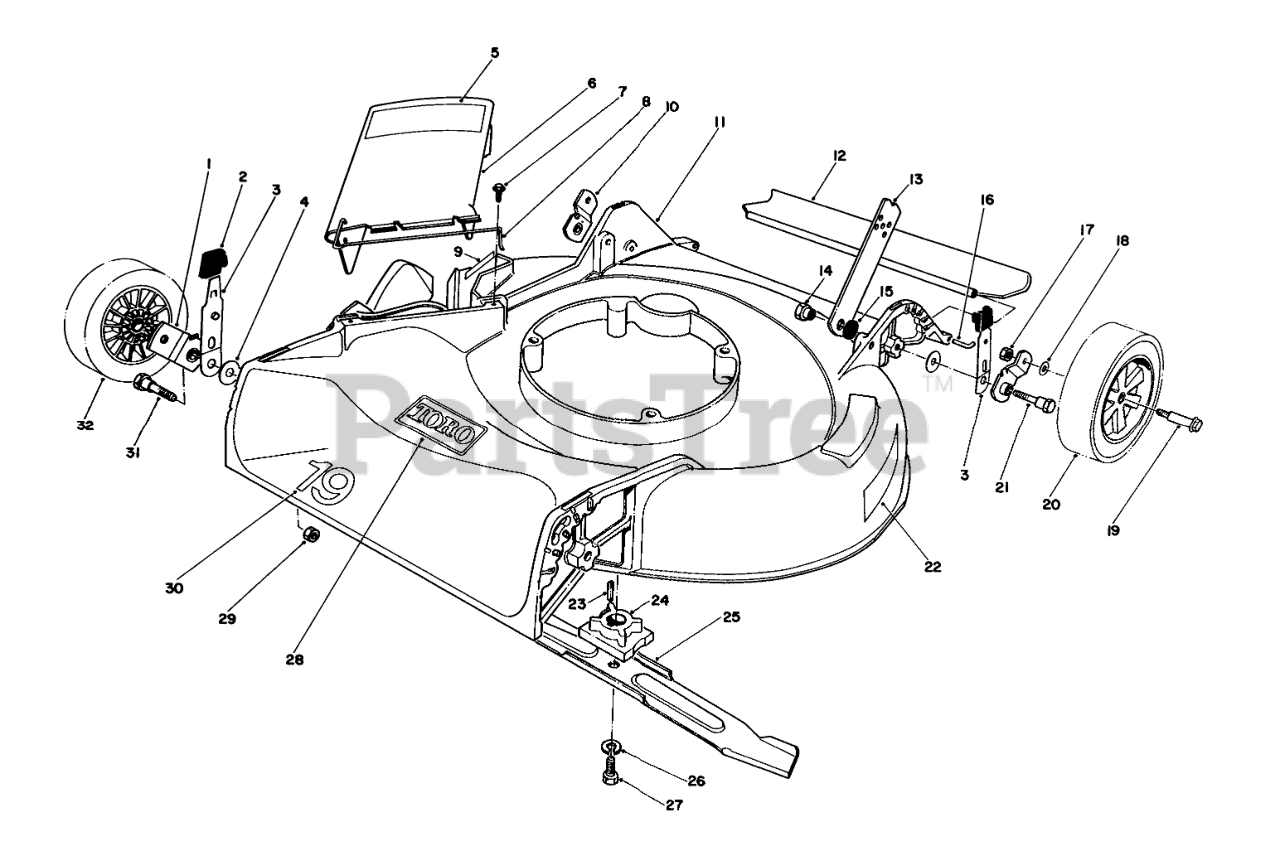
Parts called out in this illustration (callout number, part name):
1	Pivot Arm
2	KNOB-ARM
3	SPRING ARM ASM
4	WASHER-PIVOT
5	Decal-Danger
6	Deflector Assembly (Incl. Ref. #5 & 8)
7	SCREW AND WASHER ASM
8	SPRING HINGE
9	Decal-Danger
10	Pivot Arm
11	Housing 19"
12	SHIELD - TRAILING
13	HANDLE LATCH
14	HANDLE PIVOT NUT
15	HANDLE LATCH SPACER
16	SHIELD ROD
17	Nut
18	WASHER
19	BOLT-WHEEL
20	Wheel & Tire Assembly
21	PIVOT SCREW
22	Decal-Step Pad
23	KEY-SQUARE
24	Blade Retainer
25	Blade
26	WASHER-LOCK
27	SCREW-HH
28	Decal Tow
29	NUT-LOCK, NI
30	Decal-19"
31	PIVOT SCREW
32	Wheel Assembly
